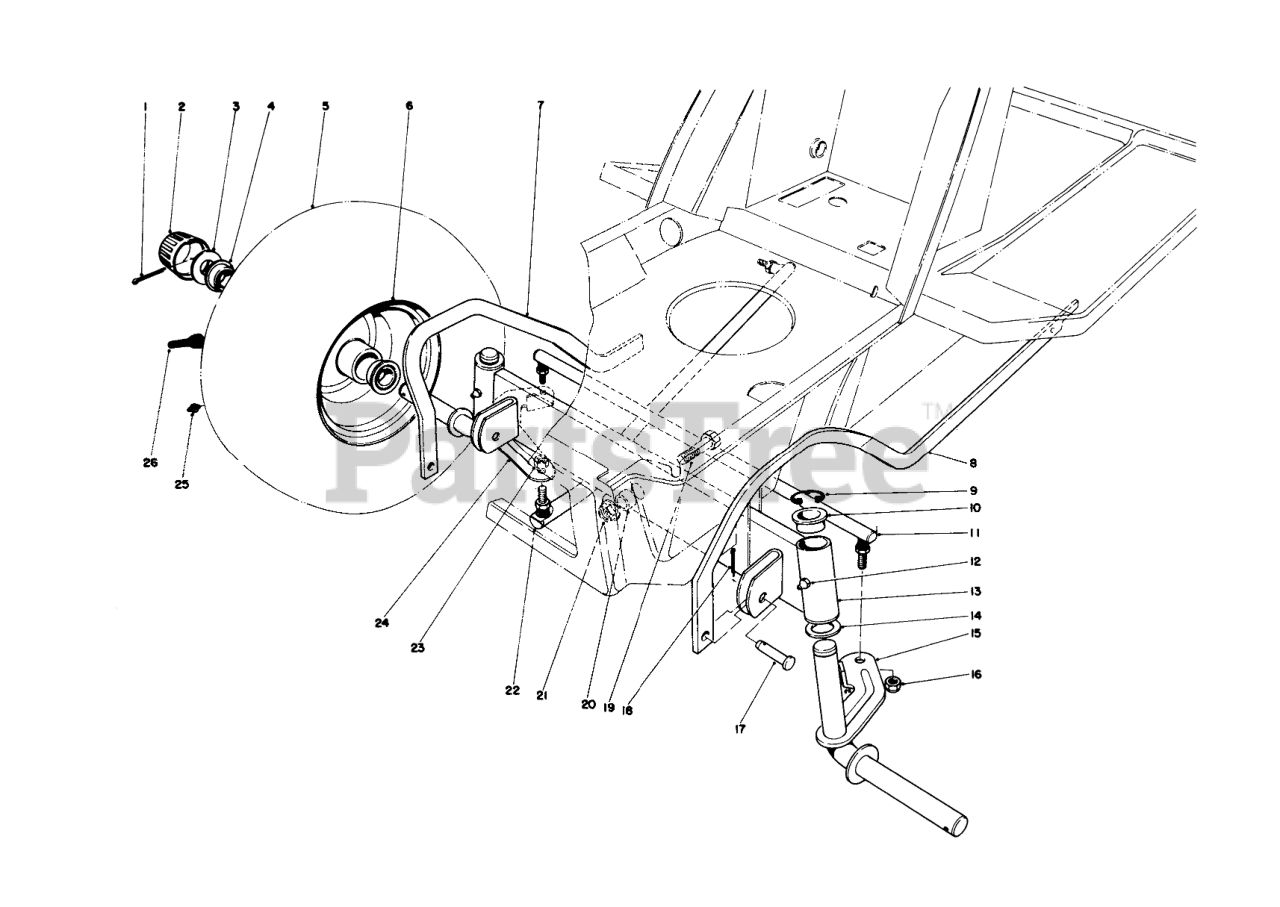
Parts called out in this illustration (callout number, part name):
1	PIN-COTTER
2	Cap-Hub
3	WASHER-PLAIN
4	Bearing
5	TIRE-FRONT
6	FRONT WHEEL
7	RH DECK PARALLEL LINK R
8	LH DECK PARALEL LNKR
9	E-Ring
10	BEARING-FLANGE
11	Tie Rod Steering
12	GREASE FITTING
13	Front Axle (Incl. Ref. #10)
14	WASHER-THRUST
15	Spindle L.H.
17	PIN-CLEVIS
18	PIN-COTTER
19	SCREW-HH
20	SPACER-AXLE, FRONT
21	NUT-HF
22	Steering Arm
23	Nut
24	SPINDLE WA RH B
25	FITTING-GREASE
26	STEM-VALVE
